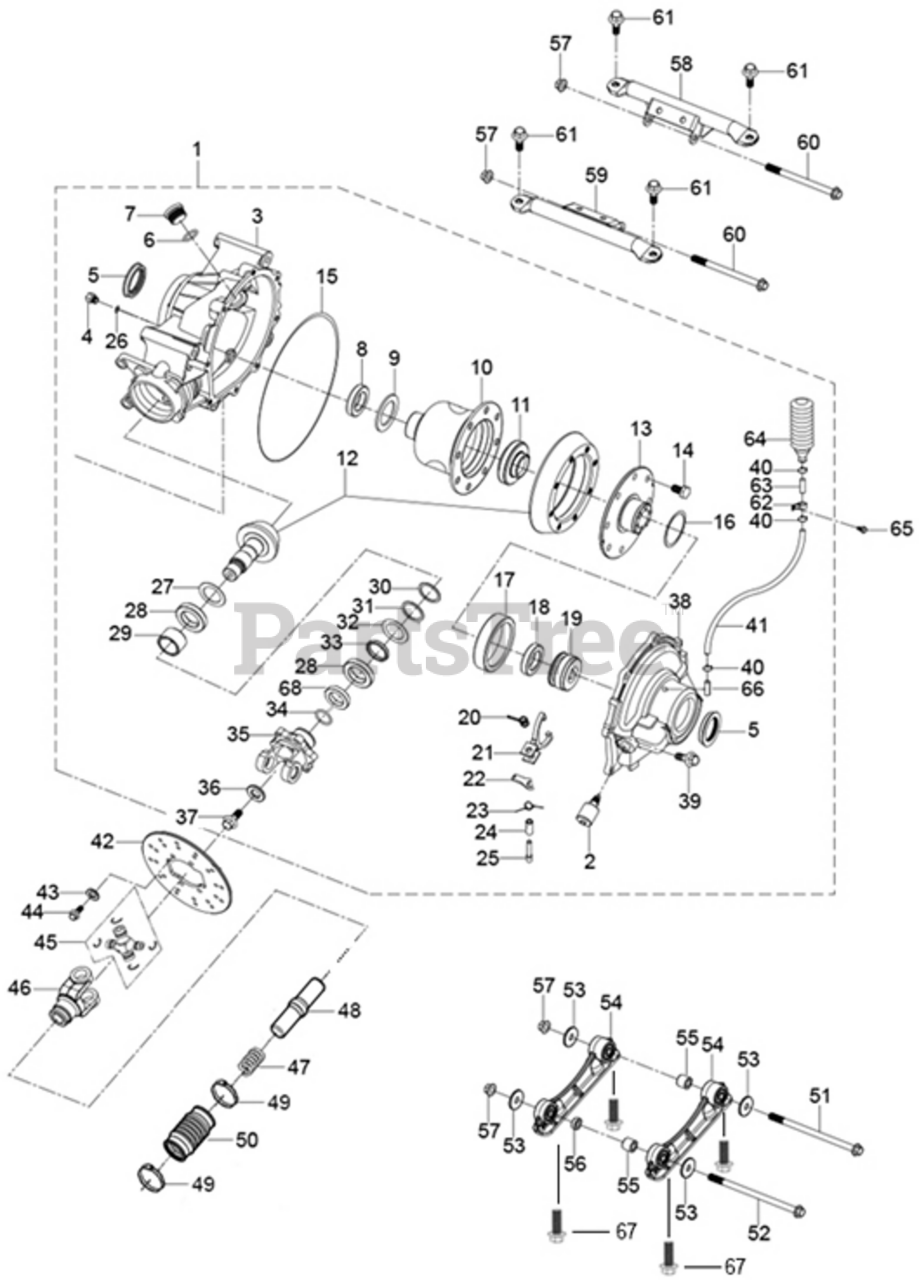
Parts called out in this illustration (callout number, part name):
1	REAR DIFFERENTIAL ASSEMBLY
2	REAR DIFF LOCK SOLENOID
3	GEARCASE - RH
4	DRAIN PLUG
5	SEAL 35X52X7
6	O-RING 23X3
7	OIL FILL PLUG
8	BEARING - ROLLER BALL 32008
9	SPACER 40.5X57X0.1
10	DIFFERENTIAL CASE
12	DIFF RING GEAR
13	SEAT SIDE GEAR
14	HEX HEAD BOLT M10X1.25-20
15	O-RING 12X192
16	SPACER 50.5X60X0.1
17	BEARING CONE
18	BEARING ROLLER BALL 32010
19	DRIVE CLUTCH
20	TORSION SPRING II
21	SHAFT FORK
22	LIMIT STOP FORK
23	TORSION SPRING I
25	BOLT STOPPER
26	O-RING 8X1
27	SPACER 30.6X46X0.1
28	BEARING ROLLER BALL 32206
29	SPACER 30.5x38x15
30	SEAL 40X72X7
31	WASHER - FLAT 30.5X38X2
32	SPACER 30.6X46X0.1
33	TUBE 30.5X38X6.4
34	O-RING 3X24
35	U-JOINT YOKE (REAR)
36	U-JOINT GASKET
37	HEX FLANGE BOLT
38	COVER GEARCASE
39	HEX HEAD FLANGE BOLT M8X25
40	CIRCLE CLIP
42	DISC BRAKE
43	SPRING WASHER-8
44	HEXAGON FLANGE BOLT M8X20
46	U-JOINT YOKE (SPLINED)
47	COMPRESSION SPRING
49	NARROW BAND CLAMP
50	NARROW BAND CLAMP I
51	HEX HEAD FLANGE BOLT
52	HEX HEAD BOLT M10X1.25-195
53	WASHER 10X35X3
54	STRAP DIFFERENTIAL-REAR SEAT
55	TUBE 10.5X20X18
56	TUBE 10.5X20X7.5
57	LOCK NUT M10X1.25
58	REAR DIFFERENTIAL BRACKET
59	REAR DIFFERENTIAL SHELF KIT -FRONT
60	HEX HEAD BOLT M10X1.25-115
61	BOLT & WASHER ASSEMBLY M8x25
62	PIPE CLAMP I
65	HEXAGON FLANGE BOLT M6X16
66	REAR DIFFERENTIAL FITTING
67	HEX BOLT & WASHER ASSEMBLY
68	LOCK SPACER
